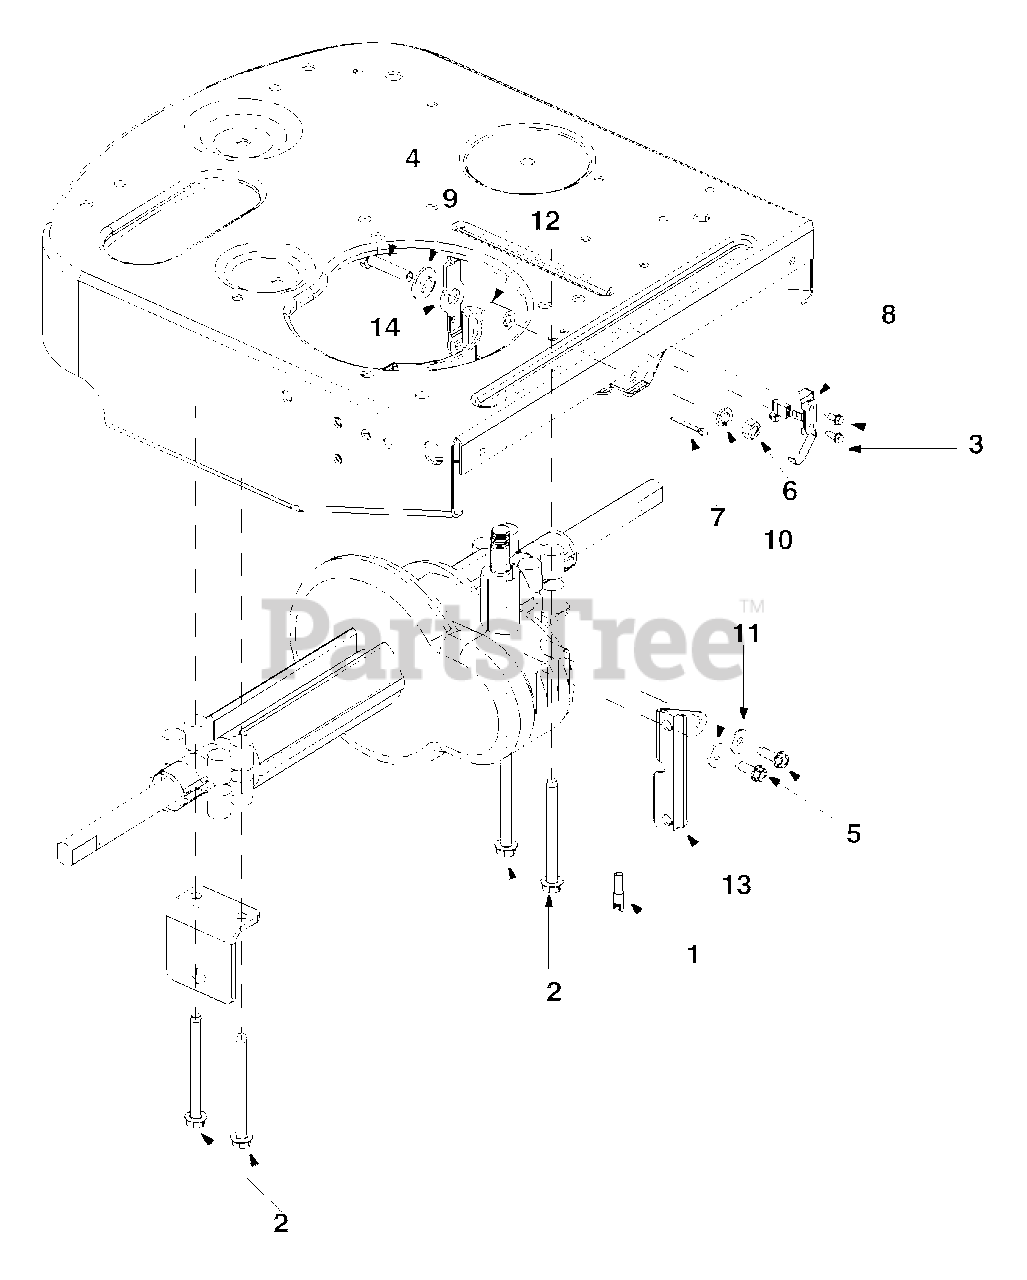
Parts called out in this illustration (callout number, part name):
1	Harness Assembly Adapter
2	Hex TT Screw 5/16-18 x 3.50
3	Hex Washer Head Self-Tap. Screw
4	Hex Screw 5/16-18 x 1.5 Gr. 5
5	Thd. Forming Scr. 1/4-20x .75
6	Hex Nut 5/16-18
8	Insulator Nut Plate
9	Shoulder Bushing
10	Lock Washer 5/16
11	Flat Washer .28 I.D. x .74 O.D. x .083
12	Spacer
